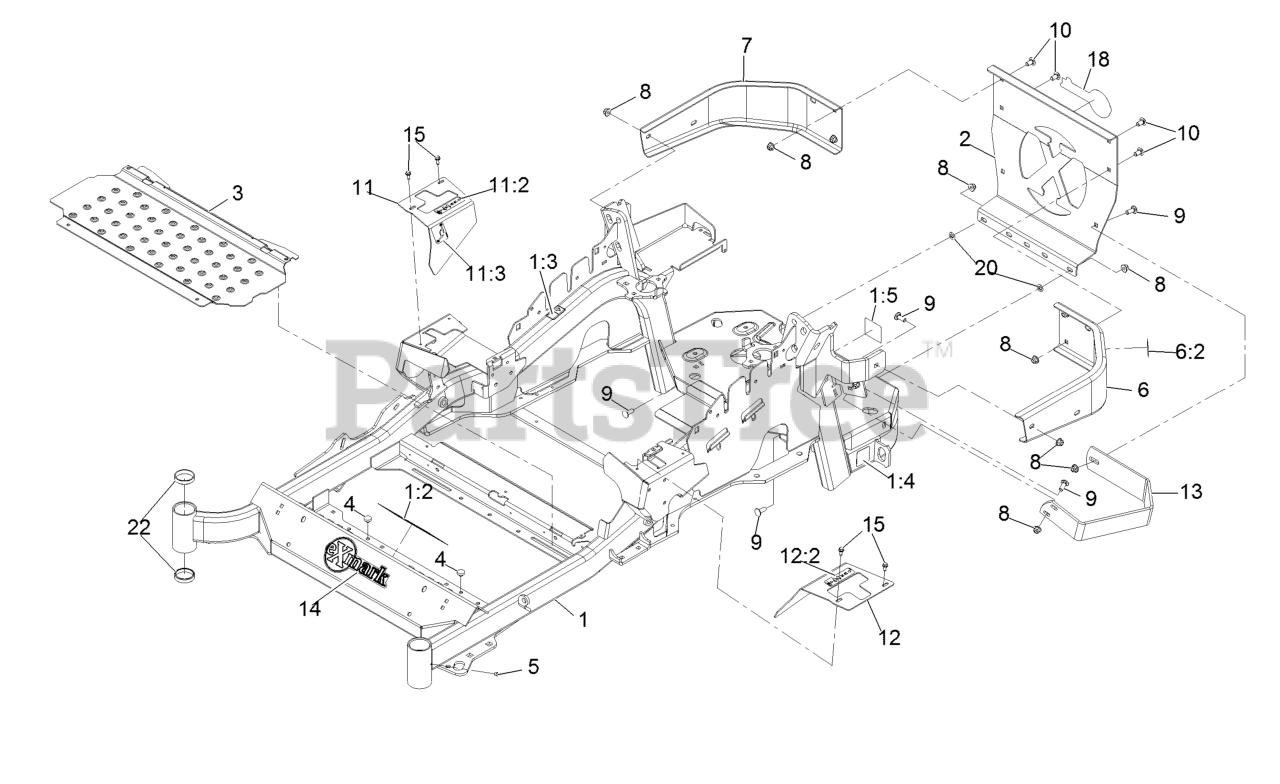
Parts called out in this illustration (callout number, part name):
1	Mainframe ASM
1:2	Decal-Danger
1:3	Decal-Warning
1:4	Decal-Hazard, Pinched Finger
1:5	Decal-Spark Arrester
2	Plate,Rear Guard
6	LH Bumper ASM
6:2	Decal-Warning
7	Bumper-RH
8	Nut-Nyloc 3/8-16 Flg
9	Bolt-Carriage 3/8-16 X 1
10	Bolt-Carriage 3/8-16 X 3/4
11	RH Motion Control Cover ASM
11:2	Decal-Control, Motion
11:3	Decal-Park Brake, CE
12	LH Motion Control Cover ASM
12:2	Decal-Control, Motion
13	Guard-Muffler
14	Decal-Exmark
15	Screw-HWH 1/4-20 X .62
18	Decal-Exmark Logo
20	Nut-Push 3/8-16
22	Cup-Bearing Tapered Roller
